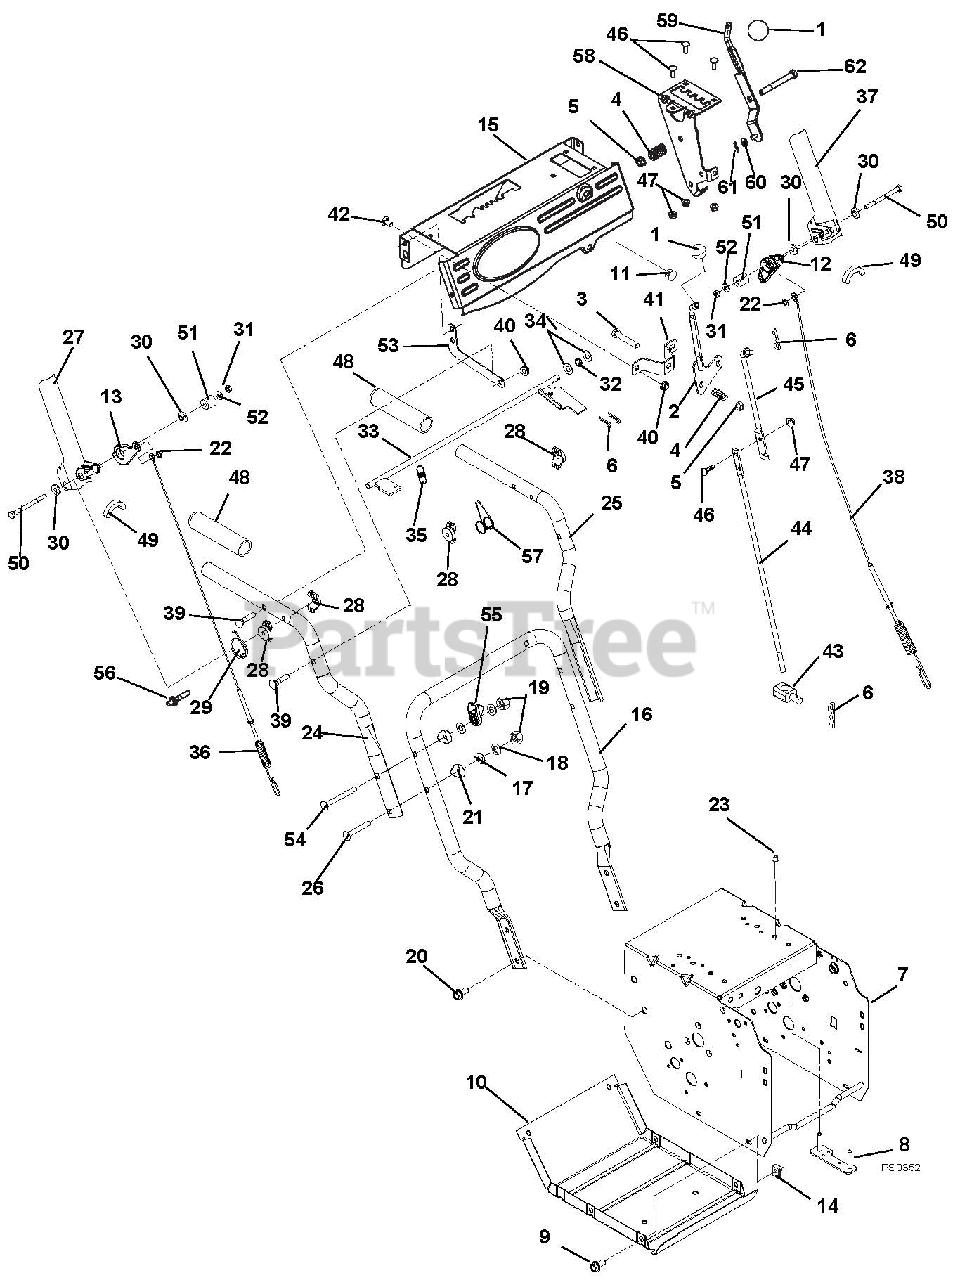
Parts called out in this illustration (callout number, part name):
1	KNOB,BALL -BLACK 1.47" .375-16
2	WMT, SHIFT LEVER
3	@BLT-HEX .38-16X2.00 GR5 YWZC
4	SG-COMP .125X.781X1.250
5	@NUT-LK-TOP-FLG .38-16 YWZC
6	PIN-HAIR INT .08X.18X1.18 YWZC
7	FRAME, 920/921
8	STRAP, ENGINE BOLT-WELDMENT
9	BLT-HEX .25-20X.75 HWH YZ GR5
10	COVER, BOTTOM
11	HOLE PLUG, PLASTIC .44 HOLE
12	CAM, INTERLOCK - LH
13	CAM, INTERLOCK - RH
14	NUT-RTNR .25-20X.56
15	CONTROL PANEL W/DECAL, REMOTE
16	HANDLEBAR, LOWER (COMPACT)
17	@WSHR-FL-STL.38X.875X.083 YWZC
18	WSHR-LK .312X.097 HVY YWZC
19	@NUT-LK-NYL .312-18 YWZC
20	BLT-SERHFWH .38-16X.75 YWZC
21	SPACER, HANDLEBAR
22	RG-RTNG-EXT .250X.010
23	RVT-POP .187 YZ
24	HANDLEBAR, UPPER - RH COMP/DEL
25	HANDLEBAR, UPPER - LH COMP/DEL
26	@BLT-RDHDSQNK .31-18X2.25 G5YZ
27	PADDLE, CLUTCH - RH COMPACT
28	SPACER, HANDLEBAR
29	SPRING, TORSION
30	BSHG, FLG .266X.42X.150 PM
31	NUT-JAM-NYL .250-20 W/INSERTYZ
32	BUSHING, POLYLINER-.38 SNAPIN
33	WELDMENT, INTERLOCK SHAFT
34	@WSHR-FL-STL.406X.812X.065 YWZ
35	SPRING, EXTENSION
36	CABLE, ATTACHMENT, COMPACT
37	PADDLE, CLUTCH - LH COMPACT
38	CABLE, TRACTION - COMPACT
39	BLT-RDHDXLSQNK .31-18X1.5 G5YZ
40	@NUT-LK-TOP-FLG .31-18 YWZC
41	BRKT, SHIFT MOUNT
42	@BLT-RHDSSQNK .31-18X1.00 G5YZ
43	PIVOT,SHIFT ROD .375-16(TRUNN)
44	ROD, SHIFT - LOWER
45	ROD, SHIFT - UPPER
46	@BLT-RDHDSQNK .25-20X.75 G5YZ
47	@NUT-LK-TOP-FLG .25-20 YWZC
48	HANDLE GRIP
49	EDGING, CLUTCH PADDLE - 2.00"
50	@BLT-HEX .25-20X3.25 YWZC
51	BSHG, SLV .266 X .750 X .750
52	@WSHR-FL-STL.281X.62X.065 YWZC
53	STRAP, CHARGE PORT
54	@BLT-RDHDSQNK .31-18X2.50 G5YZ
55	MOUNT, PLASTIC CABLE
56	STUD,.31-18X.5,.318-18X1.5
57	SPRING, TORSION, DUAL COIL
58	WMT, DEFLECTOR DETENT BRACKET
59	CONTROL, DEFLECTOR - COMPACT
60	@WSHR-FL-STL.281X.62X.065 YWZC
61	PIN-HAIR INT .06X.18X.77
62	@BLT-HEX .38-16X3.25 GR5 YWZC
